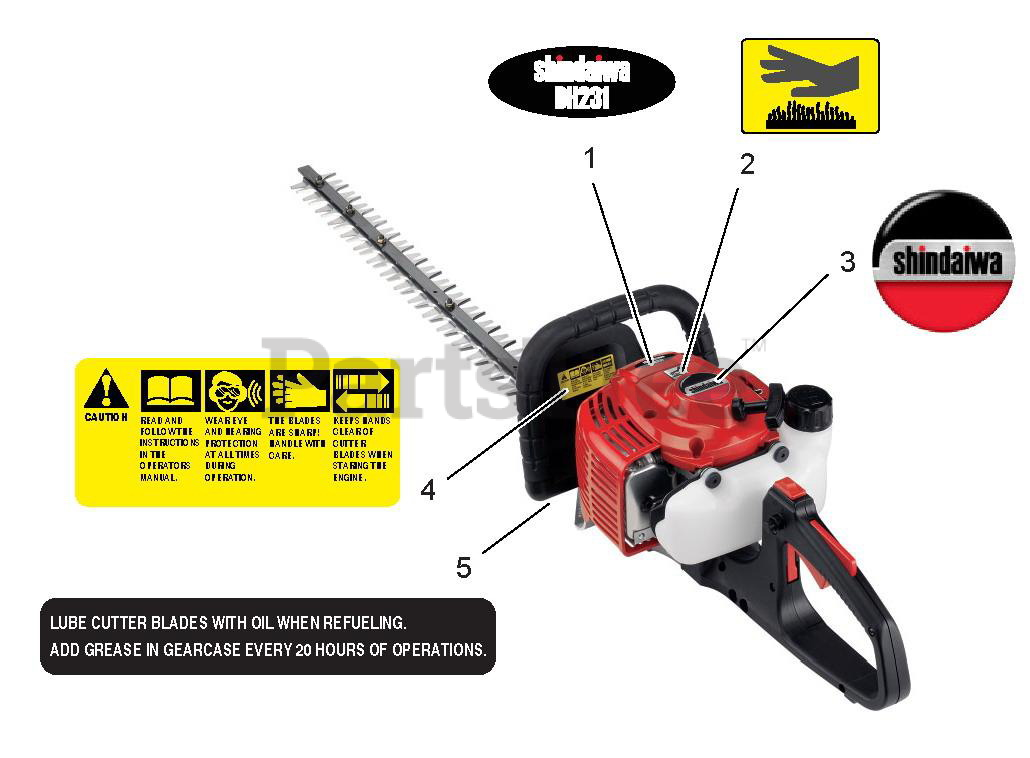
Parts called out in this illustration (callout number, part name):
1	LABEL - MODEL DH231
2	LABEL - HOT SURFACE
3	LABEL - SHINDAIWA
4	LABEL - CAUTION
5	LABEL - BLADE LUBRICATION
